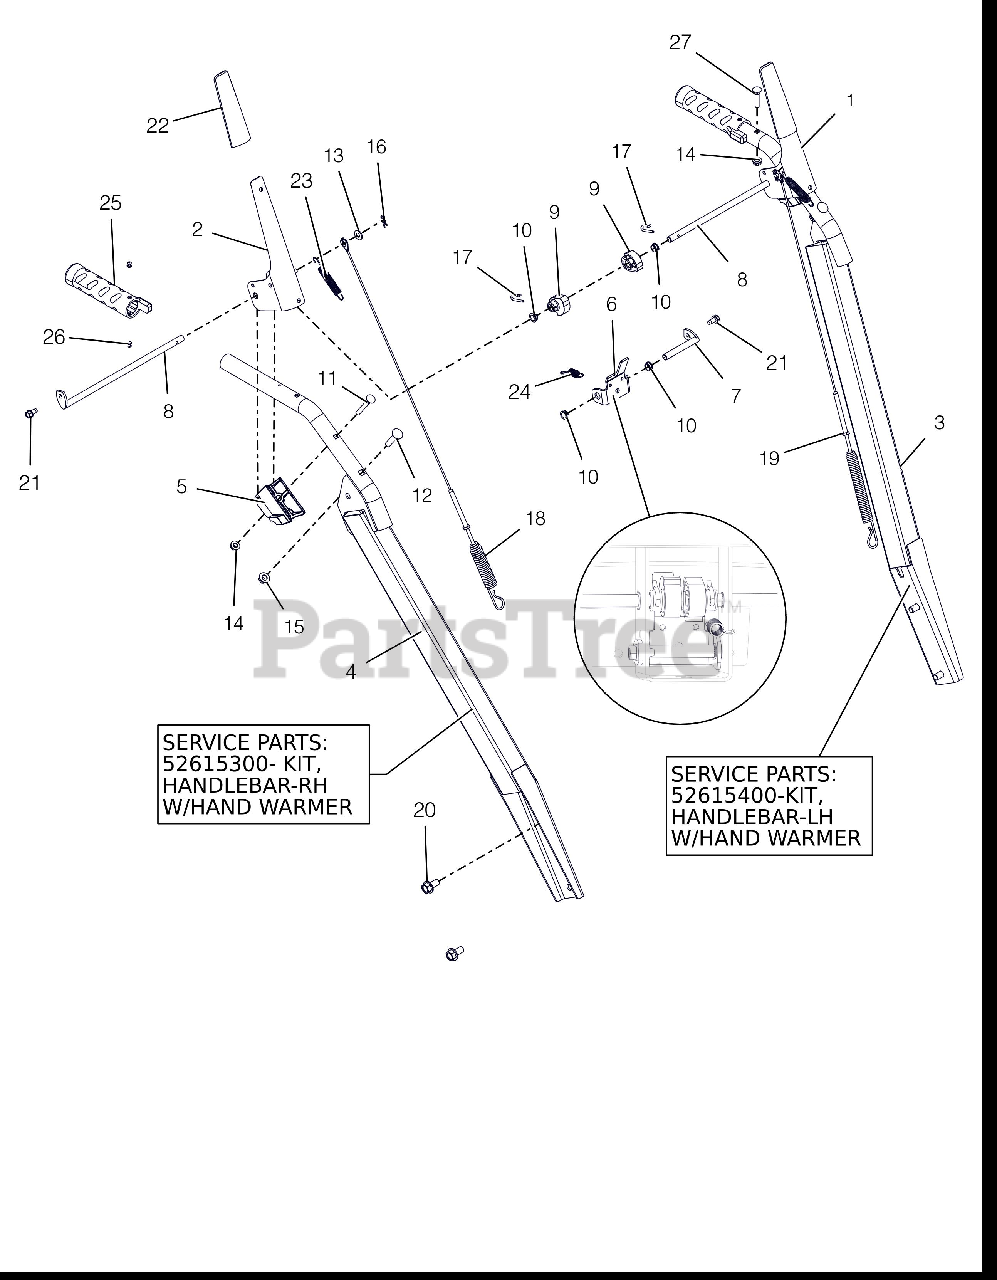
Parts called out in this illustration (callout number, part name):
1	LEVER, CLUTCH-LH
2	LEVER, CLUTCH-RH
3	HANDLEBAR, HEAVYDUTY-PRO LH
3	KIT, HANDLEBAR-LH W/WARM GRIP
4	HANDLEBAR, HEAVYDUTY-PRO-RH
4	KIT, HANDLEBAR-RH W/WARM GRIP
5	BLOCK, CLUTCH PADDLE
6	BRACKET, INTERLOCK ARM
7	ROD, PIVOT - INTERLOCK
8	ROD, PADDLE MOUNT - PRO
9	CAM, INTERLOCK
10	BUSHING, POLYLINER-.38 SNAPIN
11	BLT-RDHDXLSQNK .25-20X2.0 G5YZ
12	@BLT-RDHDSQNK .31-18X1.50 G5YZ
13	@WSHR-FL-STL.281X.62X.065 YWZC
14	@NUT-LK-CTR-FLG .25-20 YWZC
15	@NUT-LK-TOP-FLG .31-18 YWZC
16	PIN-HAIR INT .06X.18X.77
17	PIN, SPRING CLIP
18	CABLE, AUGER (DELUXE & PRO)
19	CABLE, UPPER TRACTION
20	BLT-SERHFWH .38-16X.75 YWZC
21	SCR-TAP .25-20X.50 HWH TR YWZ
22	SLEEVE, CLUTCH PADDLE-GRAY
23	SPRING, EXTENSION
24	SPRING-EXT .047X.438X1.45
25	GRIP,HEATED HANDLE-GRAY
26	RVT-POP #43 .125X.313 STL ZINC
27	BLT-RDHDXLSQNK.25-20X1.25 G5ZC
